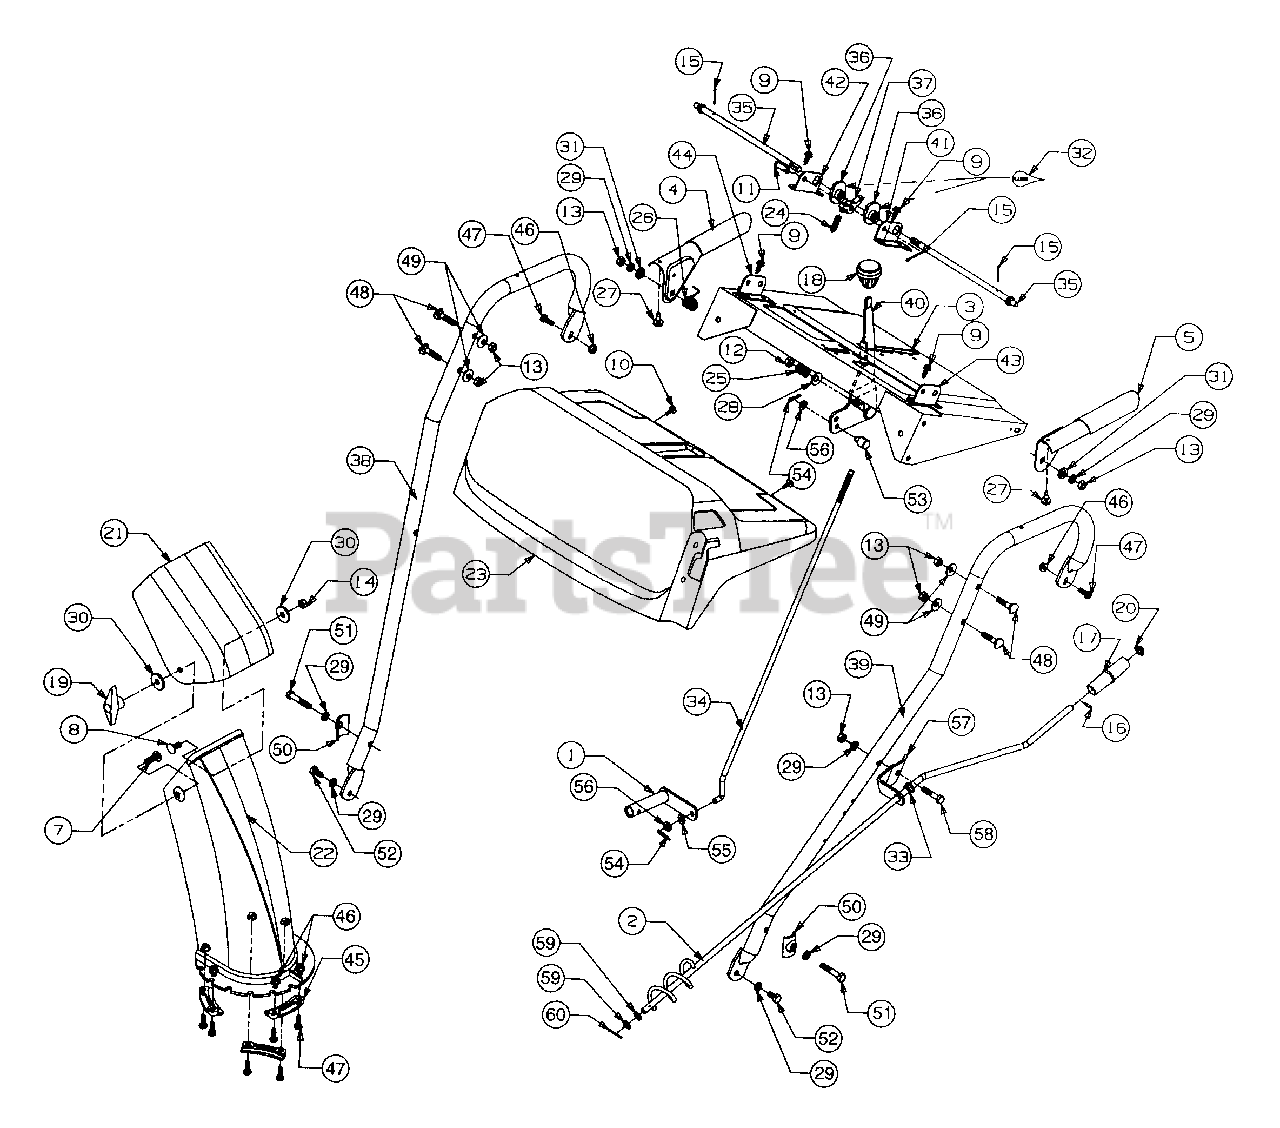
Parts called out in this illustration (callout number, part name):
1	Arm Shift
2	Crank Chute
5	Handle Grip - L.H.
7	Bolt Carriage
8	Bolt - Carriage
9	Screw
11	Pin, Clevis
12	Nut, Lock
13	Nut, Hex
14	Nut, Lock, Hex
15	Pin, Cotter
16	Roll Pin
17	Knob, Chute Crank
18	Knob, Shift
19	Knob
20	Cap, Push
21	Chute, Upper
22	Lower Chute
23	Panel, Handle
24	Spring
25	Spring
26	Spring
27	Bumper
28	Washer - Bell
29	Washer - Lock
30	Washer
31	Washer
32	Grease
33	Bushing, Plastic
34	Rod, Shift
35	Rod, Cam
36	Cam Handle Lock
37	Pawl Handle Lock
38	Handle - R.H.
39	Handle - L.H.
40	Handle Shift
41	Bracket Handle Supt. - L.H.
42	Bracket Handle Supt. - R.H.
44	Bracket Handle Supt. - R.H.
45	Chute Flange Keeper
46	Hex L-Nut 1/4-20 Thd.
47	Hex Bolt 1/4-20 x 3/4" Lg.
48	Carr. Bolt 5/16-18 x 1.5" Lg.
49	Bell-Wash. 5/16" I.D.
50	Handle Tab
51	Hex Bolt 5/16-18 x 1.75" Lg.
52	Hex Bolt 5/16-18 x 5/8" Lg.
53	Ferrule
54	Hairpin Clip
55	Spr. Wash. 5/16" I.D.
56	Fl-Wash. 5/16" I.D.
59	Fl-Wash. 3/8" I.D.
60	Cotter Pin
